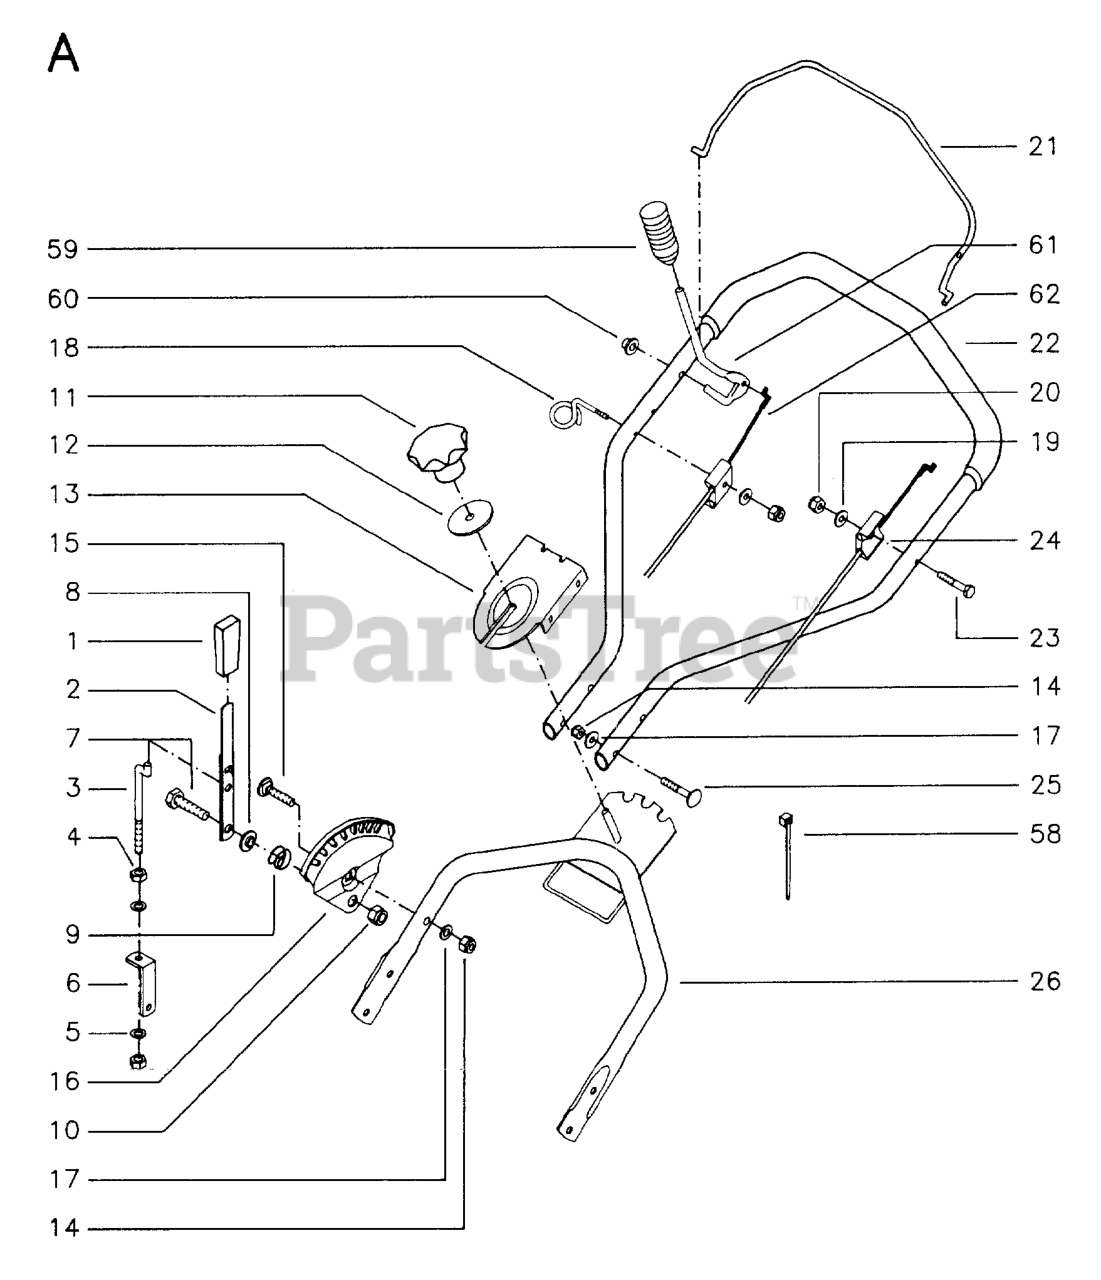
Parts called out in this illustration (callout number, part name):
2	CLUTCH ARM
4	NUT
5	STAR WASHER
9	PRESSURE SPRING
14	LOCKNUT M8
16	INDEXPLATE
17	WASHER - 15X7.3X1.6
20	LOCKNUT M6
23	BOLT FLANGE
